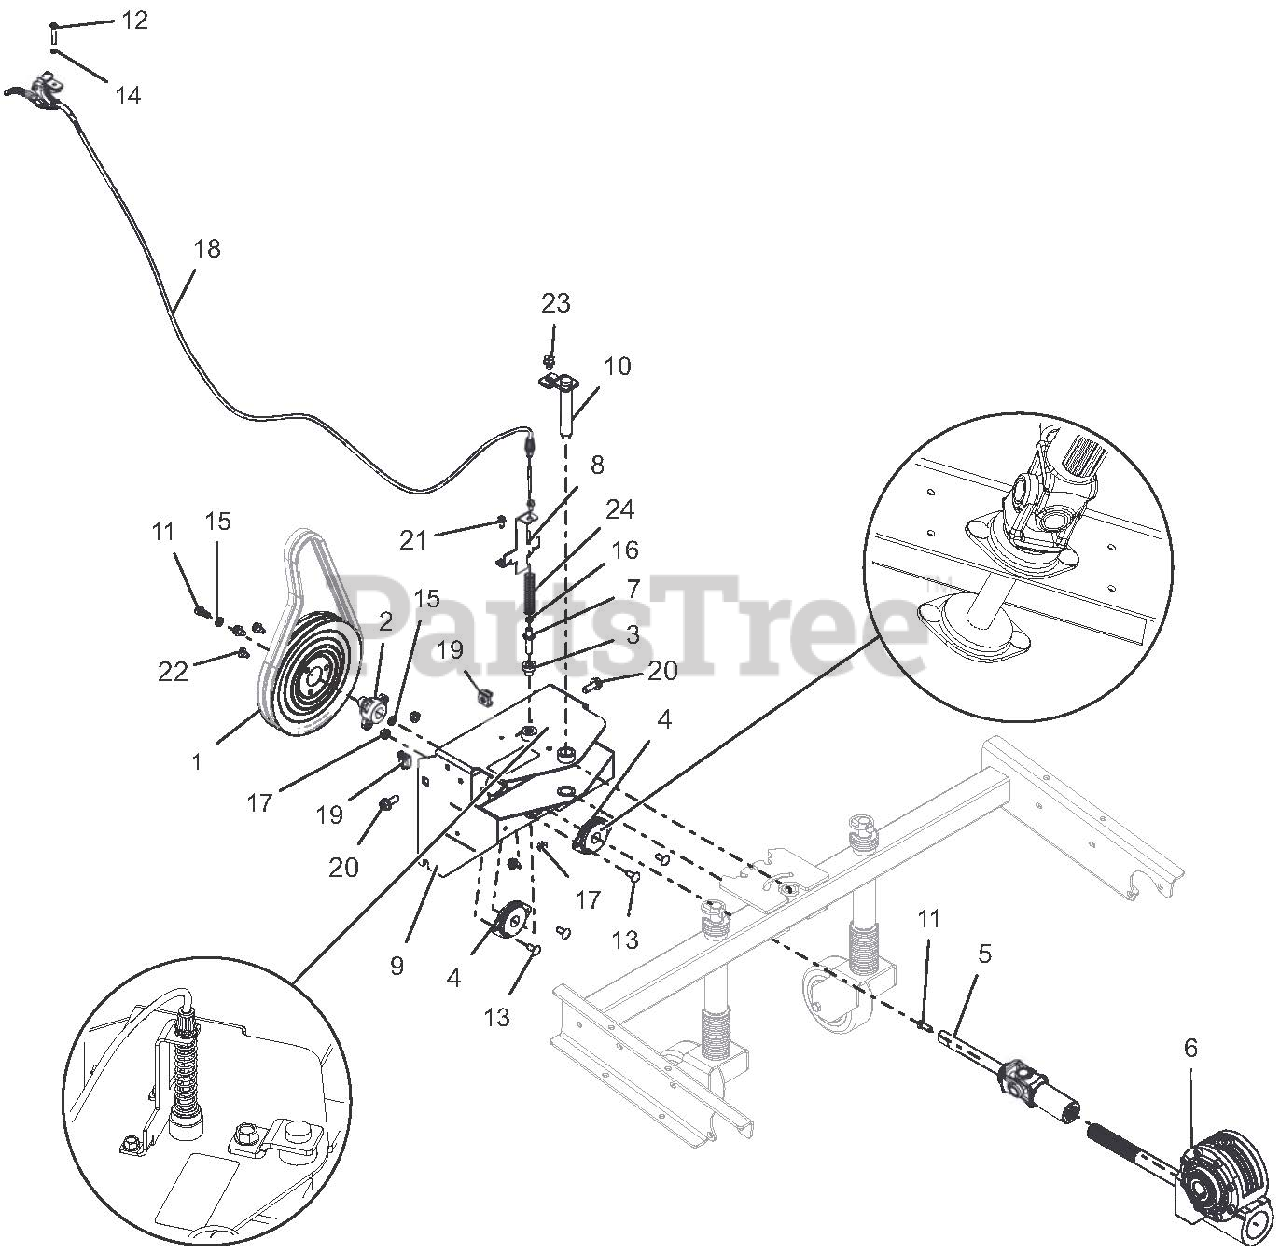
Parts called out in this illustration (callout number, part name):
1	PULLEY, DUAL GROOVE
2	HUB, ATTACHMENT PULLEY
3	SPCR, -FLANGED .390X.500X.781
4	BEARING, 2 BOLT FLANGE - .75 ID
5	DRIVELINE, SERIES 07
6	GEARBOX, WORM - 8.25:1
7	PIN, ADJUSTABLE ANGLE BRUSH
8	BRKT, PIN HOLDER
9	ADAPTOR, 36" BRUSH, 926 FRAME
10	WLDMT, BRUSH PIVOT PIN
11	BLT-HEX .31-24X.75 GR5 YWZC
12	SCR, -- MCH .25-20X1.50 OVAL HD
13	BLT-RDHDSQNK .31-18X.75 G5 YWZC
14	WSHR, LK-INT .250 TH TYA
15	WSHR-LK .31X.097 HVY YWZC
16	NUT-HEX 10-24 YWZC
17	NUT, LK-TOP-FLG .312-18 YWZC
18	CABLE, REMOTE BRUSH LOCK
19	NUT-RETAINER .38-16
20	BLT-SERHFWH .38-16X1.00 YWZC
21	SCR-TAP .25-20X.50 HWH TR YWZ
22	SCR-TAP .31-18X.50 HWH TR YWZ
23	SCR-TAP .38-16X.50 HWH TR YWZ
24	SPRG, COMPRESSION
